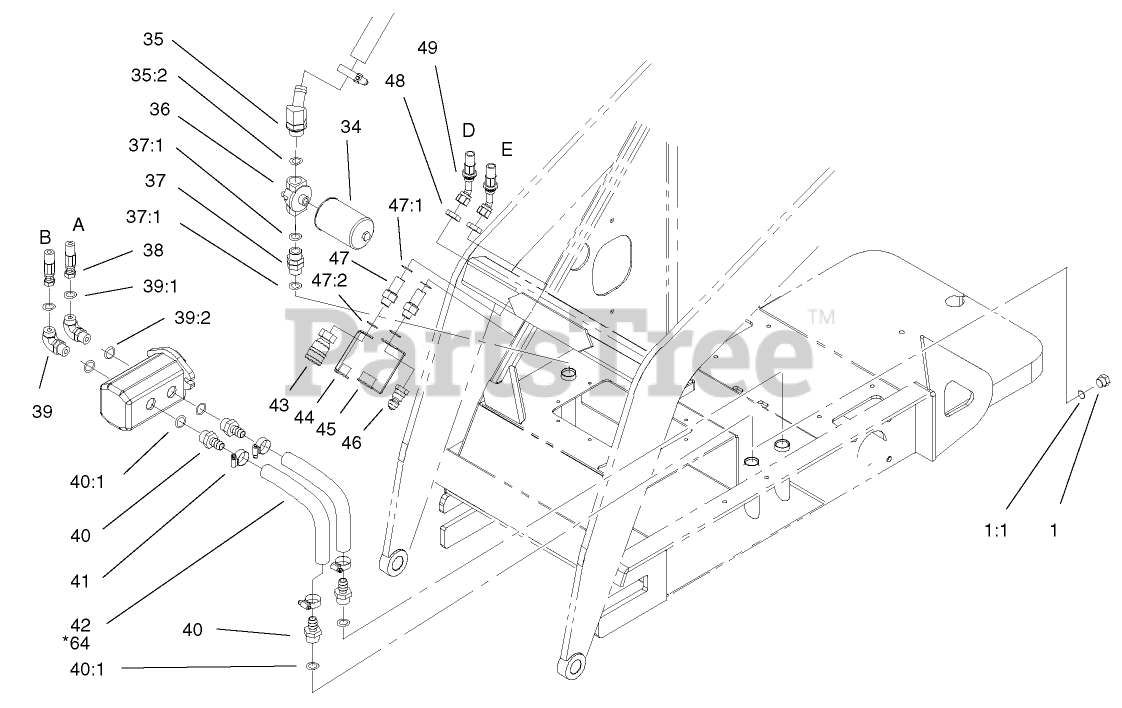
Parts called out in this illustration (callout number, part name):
1	PLUG-HEX
1:1	O-RING
34	FILTER-OIL, TRANSMISSION
35	FITTING-45 DEG
35:2	O-RING
36	HEAD-FILTER
37	FITTING-THREAD, STRAIGHT
37:1	O-RING
38	HOSE-HYD
39	FITTING-ELBOW 90
39:1	O-RING
39:2	O-RING
40	FITTING-STRAIGHT
40:1	O-RING
41	CLAMP-HOSE
42	HOSE-SUCTION, HYD
43	FEMALE-DISCONNECT, QUICK
44	Dust Plug
45	Cap-Dust
46	MALE-DISCONNECT, QUICK
47	UNION-BULKHEAD
47:1	O-RING
47:2	O-RING
48	NUT-BULKHEAD
49	HOSE-AUX, HYD
64	Spring-Compression
